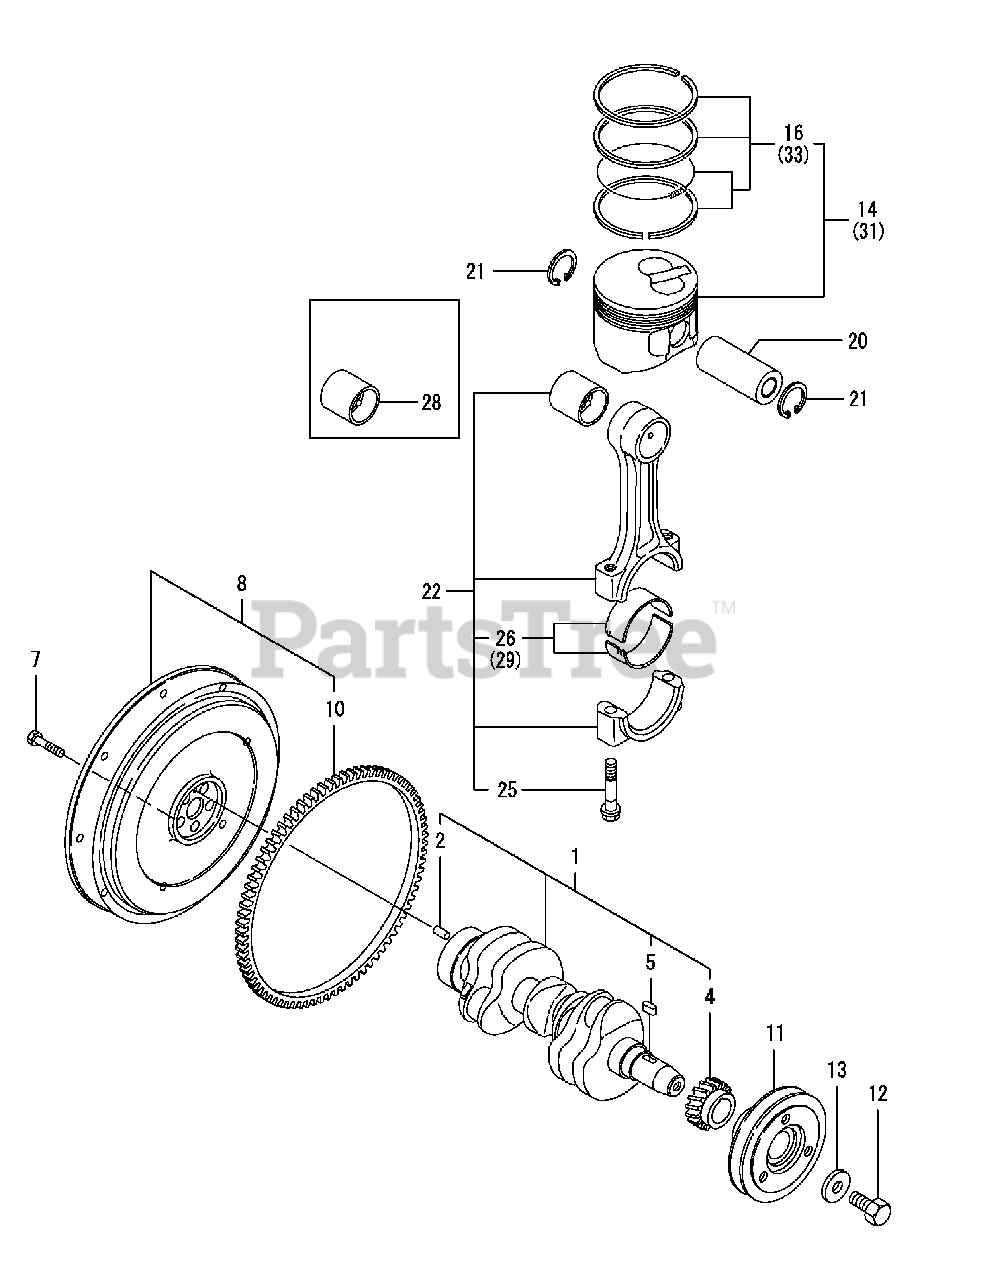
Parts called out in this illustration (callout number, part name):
1	Crankshaft Assembly
2	Parallel Pin 8 x 16
4	Gear, Crankshaft
7	Bolt, Flywheel
8	Flywheel Assembly
11	V-Pulley, Crankshaft
12	Bolt M12 x 1.25, Flange
14	Piston Assembly
22	Rod Assembly, Connecting
25	Bolt, Connecting Rod
26	Metal Assembly, Crank Pin
28	Bush, Piston Pin
31	Piston Assembly
